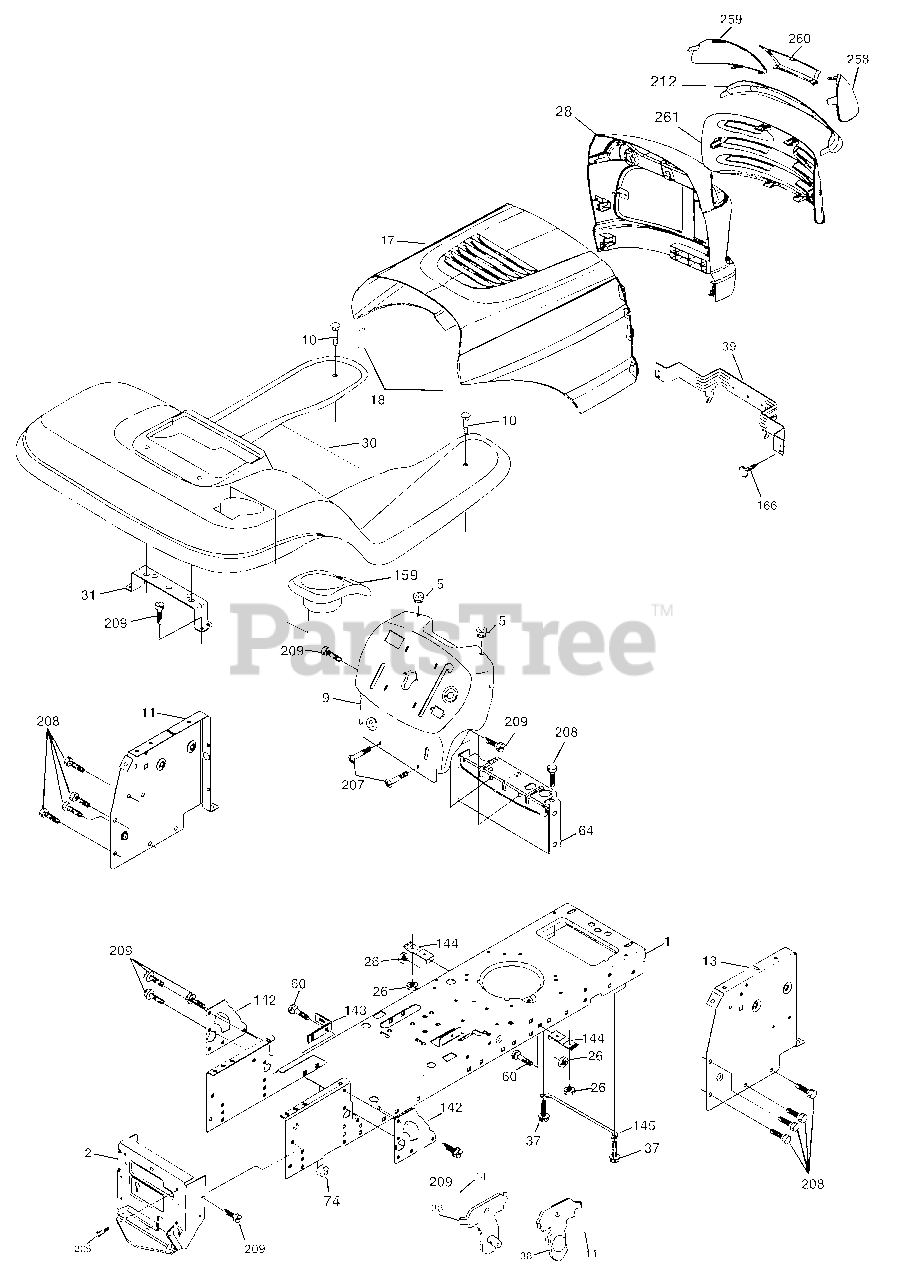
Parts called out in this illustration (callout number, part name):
1	Chassis Stamping
2	Drawbar, 12 Ga.
5	Bumper Hood/Dash
9	Dash Slkscr
10	Bolt Carriage 3/8-16 x 1
11	Panel Dash Lh
13	Panel Dash Rh
14	Screw Thdrol 3/8-16 x 1/2
17	Hood
18	Bumper Hood
26	Nut Lock Hex W/Ins 3/8-16 unc
28	Grille/Lens Asm
30	Fender Footrest
31	Bracket Fender
37	Screw Thdrol 6/16-18 x 1/2 TYT
38	Bracket Asm Pivot Mower Rear
39	Bracket Pivot
60	Bolt Rd Hd Sqnk 3/8-16 Unc x 3/4
64	Dash Lower STLT
74	Nut Crownlock 3/8-16 Unc
142	Plate Reinforcement STLT
143	Bracket Swaybar Chassis
144	Bracket Footrest
145	Rod Pivot Chassis/Hood
159	Cupholder
166	Screw Hw Hd Hi-Lo #13-16 x 3/4
206	Bolt Shoulder 5/16-18 TT
207	Screw Thdrol 5/16-18 x 1/2
208	Screw Thdrol 3/8-16x1/2 Ty-tt
209	Screw Hex Wsh Thdr. 3/8-16 x 3/4
212	Insert Lens Reflective
258	Lens Husq Laser LT Clear RH
259	Lens Husq Laser LT Clear LH
260	Cover Lens
261	Insert Grille
